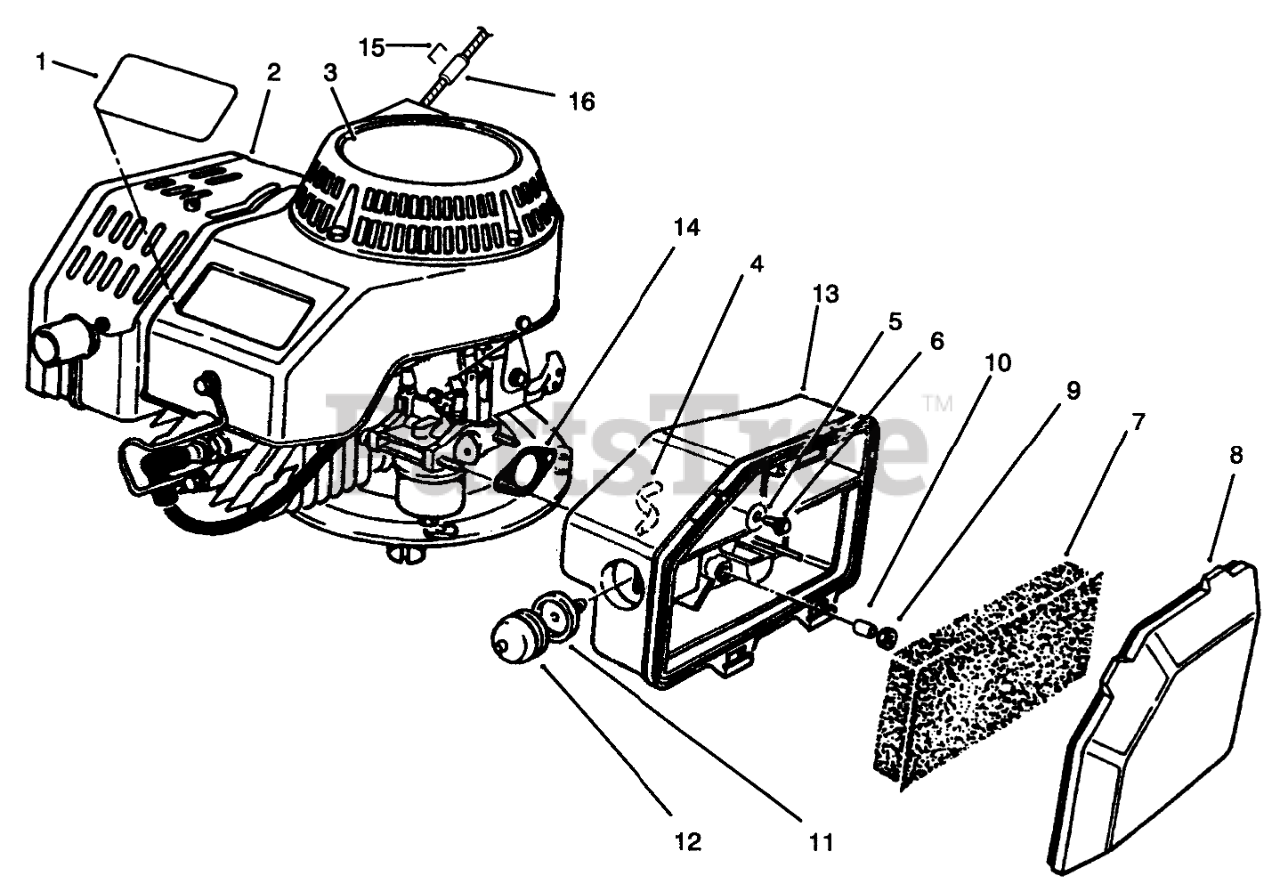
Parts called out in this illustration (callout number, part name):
1	DECAL - PROLINE
2	ENGINE ASM
3	DECAL-2 CYC RECOIL COMM
4	HOSE-PRIMER
5	WASHER-FLAT
6	SCREW-HH
7	ELEMENT-AIR CLEANER
8	COVER-AIR CLEANER
10	SPACER
11	BODY-PRIMER
12	BULB-PRIMER
13	BODY-AIR CLEANER
14	GASKET-AIR CLEANER
15	Staple
16	STOP-ROPE
